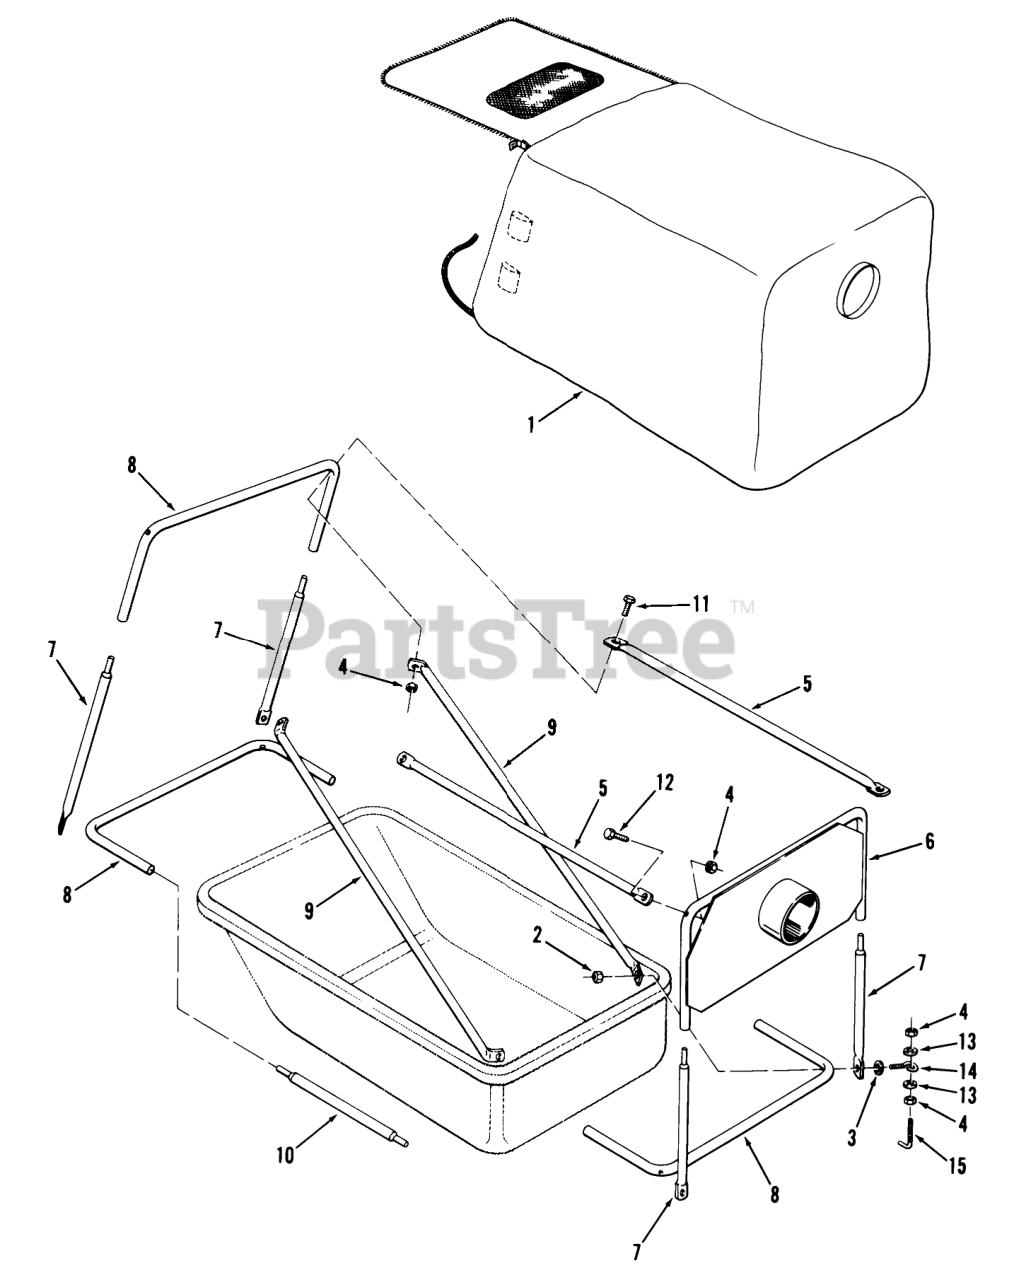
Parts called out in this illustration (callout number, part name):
1	Cart Cover
2	Nut
4	Nut
5	Top Tube
6	Front Hose Adapter
7	Upright Brace
8	U-Tube
9	Cross Tube
10	Side Tube
11	Bolt
12	Bolt
13	WASHER 5/16 SAE
14	EYE BOLT
15	J-Bolt
